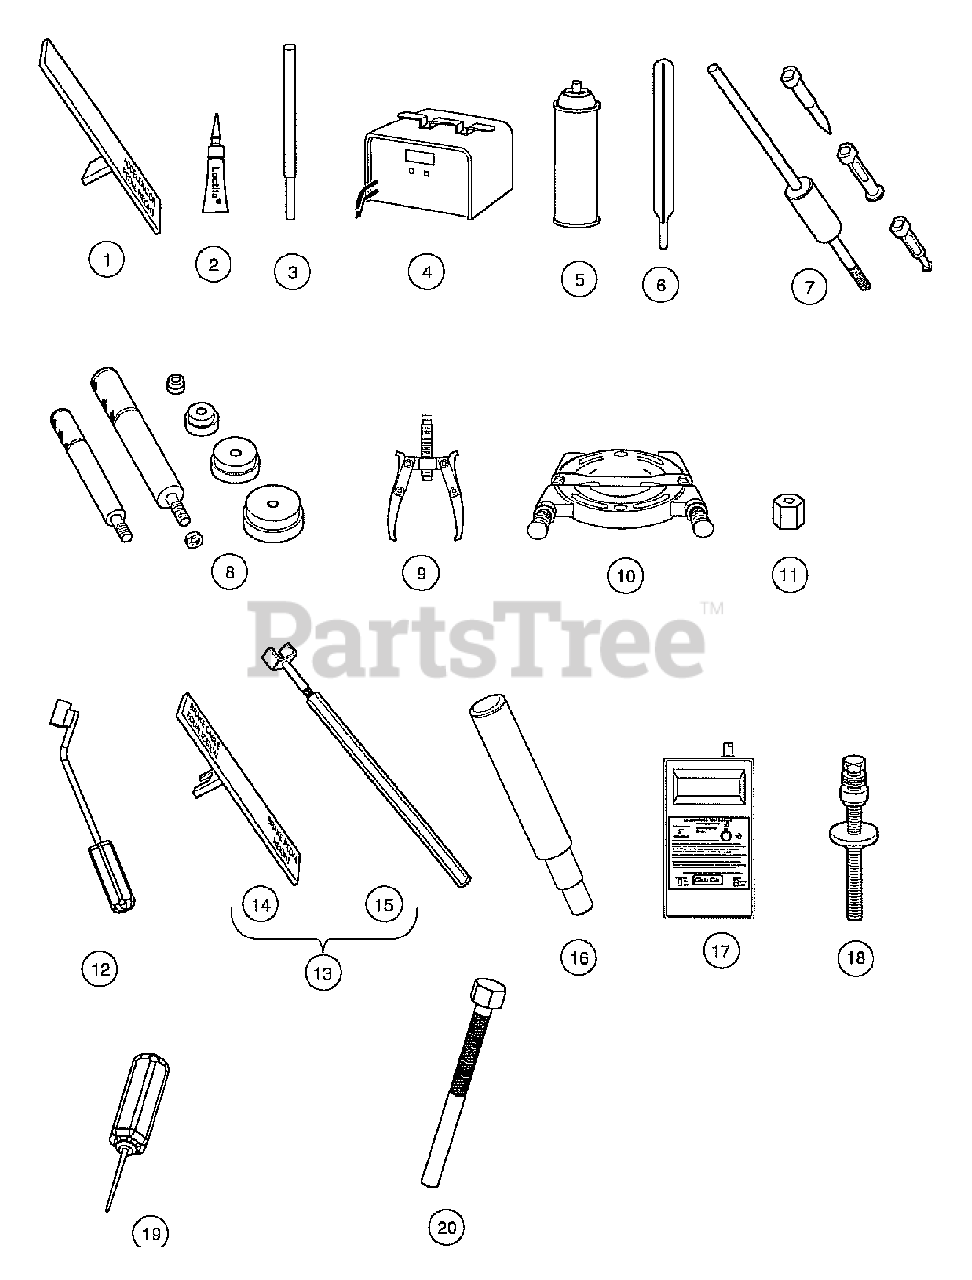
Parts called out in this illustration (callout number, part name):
1	Accelerator Pedal Adjustment Tool
2	Adhesive, Guide Ring, 3-Gram Tube
4	Battery Discharge Machine, 36/48 Volt
5	Battery Terminal Protector Spray
6	Battery Thermometer
7	Bearing and Oil Seal Remover Assembly
8	Bearing Driver Set
9	Bearing Puller
10	Bearing Puller Wedge Attachment
11	Brake Adjustment Tool
12	Brake Cable Release Tool
13	Brake Pedal Adjustment Tool Kit
14	Brake Pedal Adjustment Tool
15	Brake Pedal Tension Tool
16	Connecting Rod Small End Bushing Tool
17	Calibration Test Module
18	Cam Installation Tool
19	Charger Bezel Tool
20	Clutch Removal Tool
